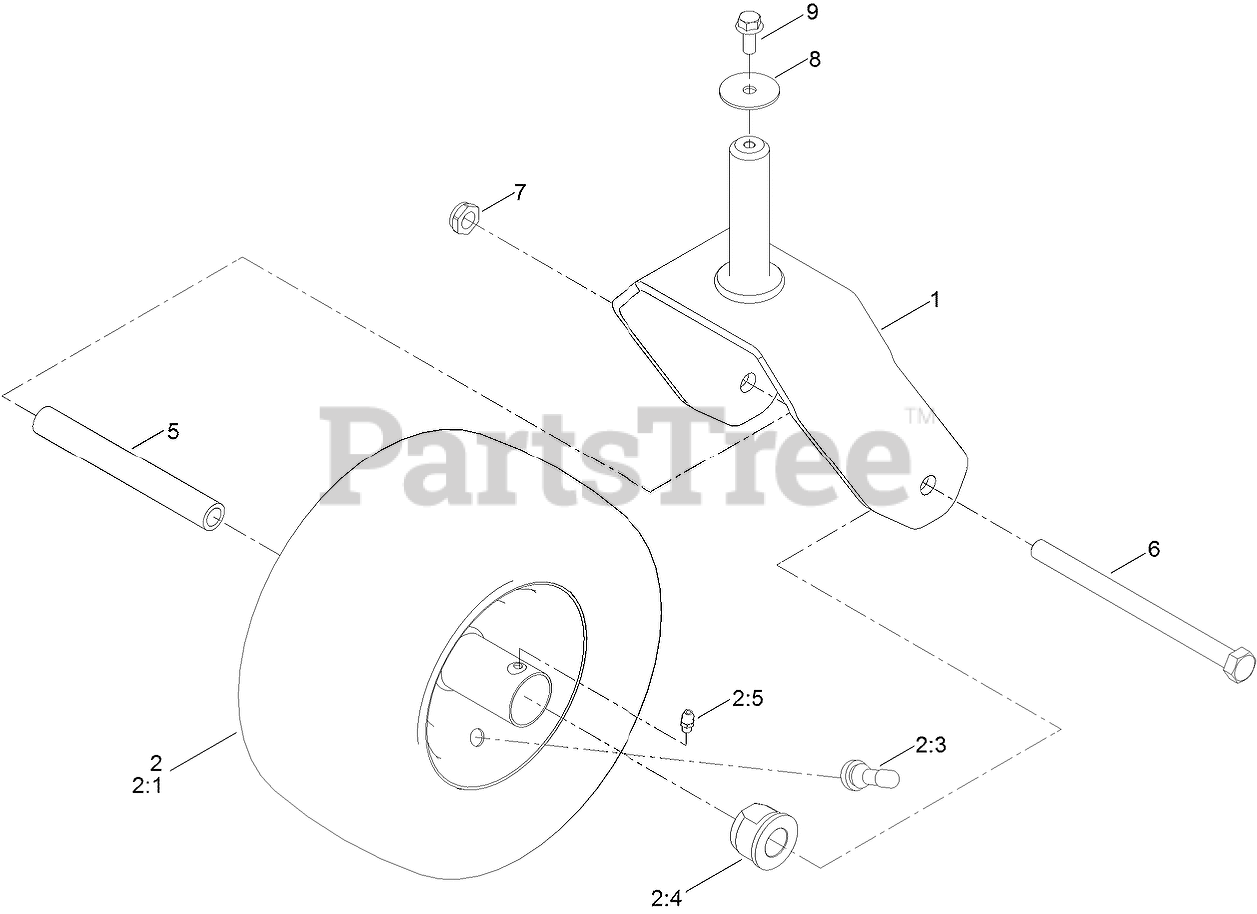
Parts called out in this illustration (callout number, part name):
1	FORK ASM
2	TIRE ASM
2:4	BUSHING-FLANGE
2:5	FITTING-GREASE
5	SPACER-SPANNER
6	SCREW-HH
7	NUT-LOCK, NI
8	WASHER-FLAT
9	SCREW-HHF
